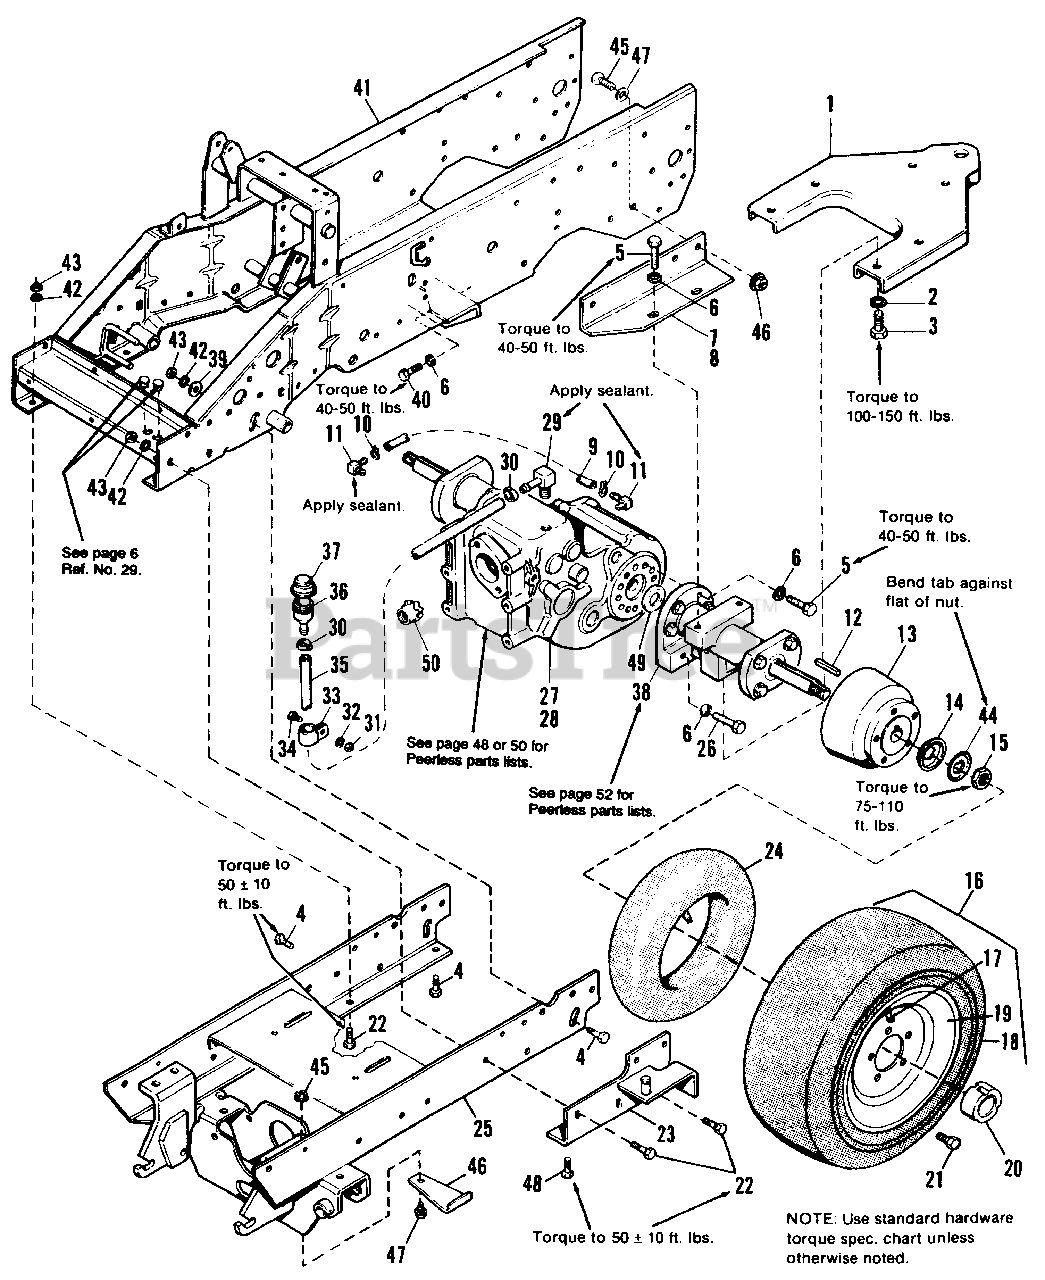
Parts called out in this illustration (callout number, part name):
2	LOCKWASHER, 5/8"
3	CAPSCREW, Hex Hd., 5/8-11 x 1-1/4
4	CAPSCREW, Hex Hd., 7/16-14 x 1, Gr. 5
5	CAPSCREW, Hex Hd., 1/2-13 x 1-1/2
6	LOCKWASHER, 1/2
7	SUPPORT, Transmission, R.H.
8	SUPPORT, Transmission, L.H.
9	HOSE, Fluid Level
10	CLAMP, SAE #6
11	FITTING, Elbow
12	KEY, 5/16 x 5/16 x 2-1/2
13	DRUM, Brake
14	RETAINER, Hub Cap
15	NUT, Hex, Jam Centerlock, 1-14
16	WHEEL & TIRE ASSY., 23 x 10.5-12 (Beige)
16	WHEEL & TIRE ASSY., 23 x 10.5-12 (Silver)
16	WHEEL & TIRE ASSY., 26 x 12.00-12 (Beige)
16	WHEEL & TIRE ASSY., 26 x 12.00 12 (Silver))
17	VALVE STEM & CAP
18	TIRE, Turf, 23 x 10.5-12
18	TIRE, Turf, 26 x 12.00-12
19	WHEEL, 23" (Beige)
19	WHEEL, 23" (Silver)
19	WHEEL, 26" (Beige)
19	WHEEL, 26" (Silver)
22	CAPSCREW, Hex Hd., 7/16-14 x 1-1/4, Gr. 5
23	BRACKET ASSY., Power Steering Cylinder
25	FRONT FRAME ASSY.
26	CAPSCREW, Hex Hd., 1/2-13 x 2
29	FITTING, Hose, 90ø
30	CLAMP, Hose
31	NUT, Hex, 1/4-20
32	LOCKWASHER, 1/4
33	CLAMP, Insulated
34	CAPSCREW, Hex Hd., 1/4-20 x 3/4
35	HOSE, Fill, 1/2" I.D.
36	NECK, Filler
37	CAP, Filler
39	WASHER, Plain, 1/2
40	CAPSCREW, Hex Hd., 1/2-13 x 1-1/4
41	FRAME ASSY., Rear
42	LOCKWASHER, 7/16
43	NUT, Hex, 7/16-14
44	RETAINER NUT
45	CAPSCREW, Hex Hd., 7/16-14 x 1-1/4
46	NUT, Hex Flange, 7/16-14
47	WASHER, Plain
48	CAPSCREW, 7/16-14 x 1-1/2
49	SPACER, Axle
50	GEAR, Bevel
